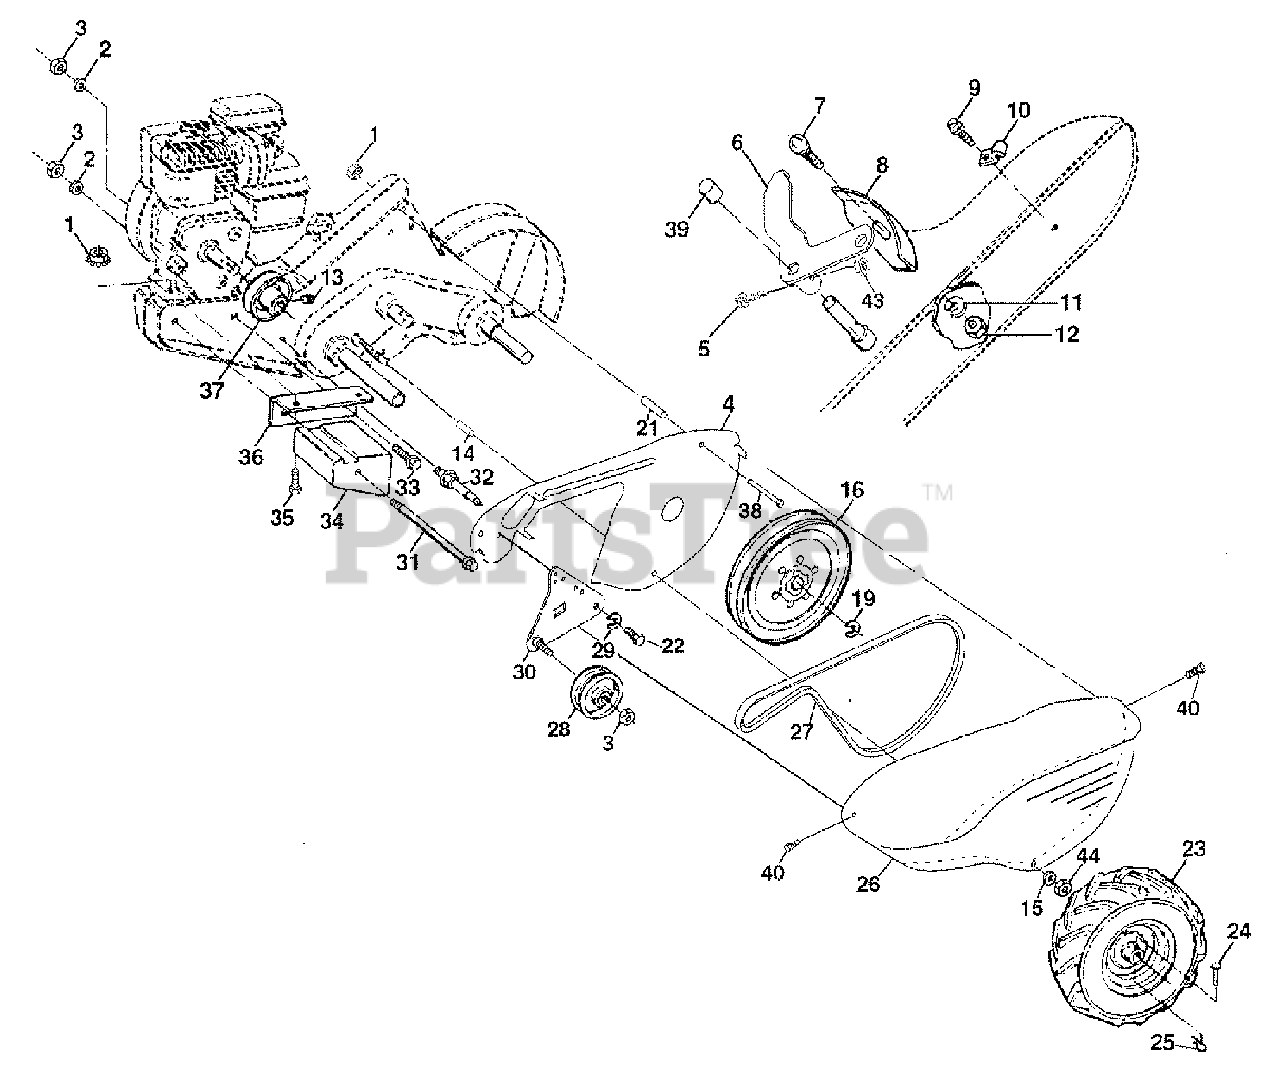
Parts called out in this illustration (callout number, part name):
1	Nut, Keps 5/16-18
2	Washer, Lock 3/8
3	Nut, Hex 3/8-16
4	Shield, Inner Belt Guard
5	Screw, Shift Lever
6	Lever, Shift
7	Bolt, Carriage 1/4-20 x 1/2 Gr. 5
8	Plate, Shift Indicator
9	Screw, Hex, Washer Head, Slotted #10-24x1/2
10	Clip
11	Washer, Lock 1/4
12	Nut, Hex 1/4-20
13	Screw, Set, Hex 5/16-18x3/8
14	Spacer, Split 0.327 x 0.42 x 1,220
15	Washer 11/32 x 11/16x16Ga.
16	Sheave, Transmission
19	Ring, Retainer
21	Spacer, Split 0.327 x 0.42 x 2.09
22	Bolt, Fin Hex 5/16-24x1/2
23	Tire
23	Tire Valve
24	Rivet, Drilled
25	Clip, Hairpin
26	Guard, Beit
27	Belt, V
28	Pulley, Idler
29	Ring, Klip
30	Bracket, Idler
31	Bolt, Hex 5/16-16x12
32	Shaft, Idler Arm
33	Bolt, Hex 3/8-16x1
34	Counterweight, LH.
35	Bolt, Hex 5/16-18x1-1/2
36	Bracket, Reinforcement, L. H.
37	Sheave, Engine
38	Bolt, Fin Hex 5/16-18 x 2-3/4
39	Cap, Plunger
40	Screw Hex Wsh Sit # 10-24 x .50
43	Nut, Lock #10-24
44	Nut, Lock 5/16-18
